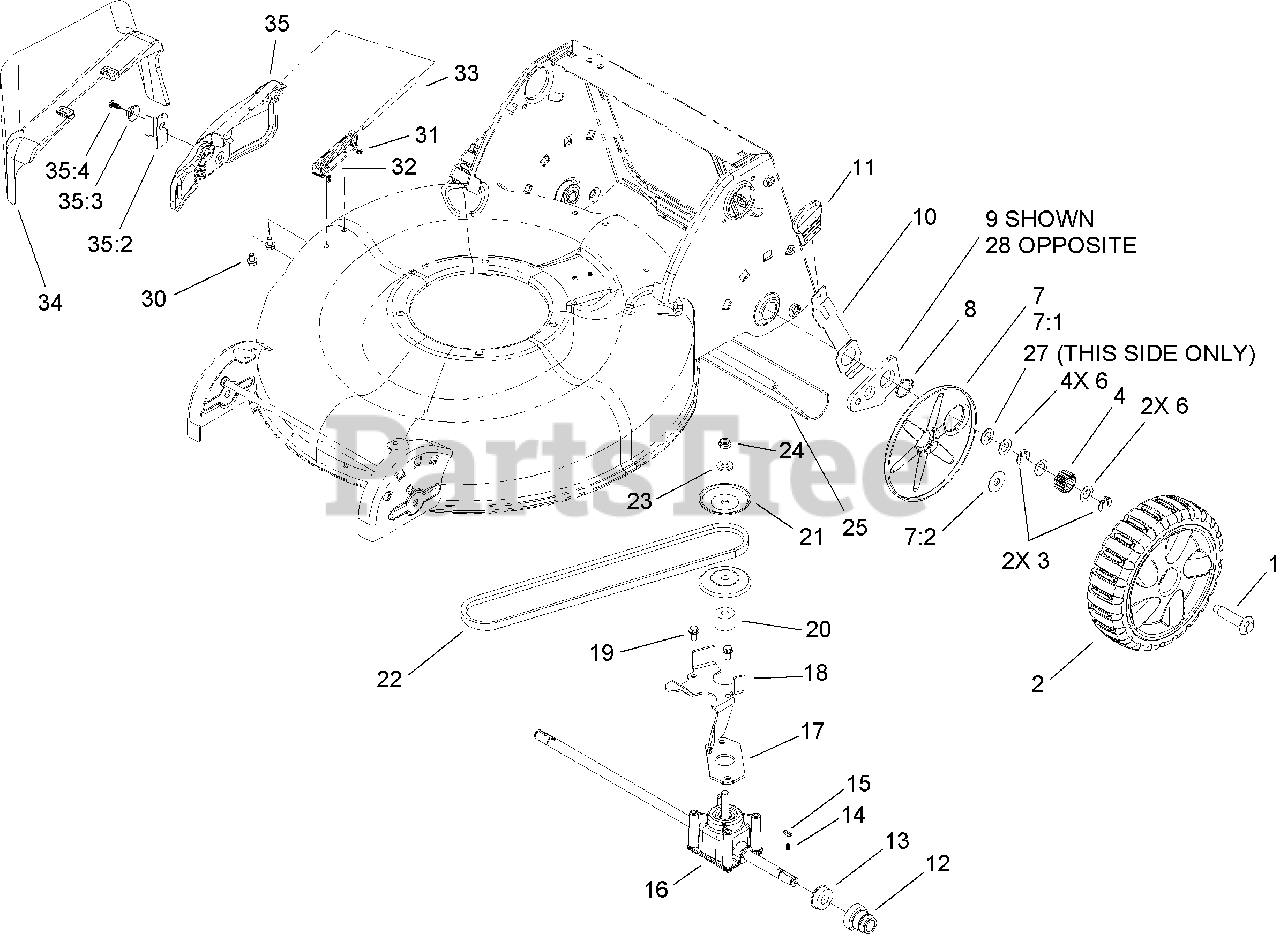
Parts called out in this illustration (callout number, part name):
1	BOLT-SHOULDER
2	REAR WHEEL ASM
3	KLIPRING-LOCKING
4	Gear-Pinion, 15t
6	Washer-Thrust
7	WHEEL COVER ASM
7:1	COVER-WHEEL
7:2	WASHER-STEPPED
8	RING-RETAINING
9	ARM-REAR PIVOT, LH
10	ARM-SPRING, REAR
11	KNOB-LEVER, HOC
12	RETAINER-BEARING, HOC
13	BEARING-BALL
14	SPRING-COMPRESSION
16	TRANSMISSION ASM
17	GASKET-GEARBOX
18	BRACKET-TRANSMISSION
19	SCREW-HWH
21	PULLEY-HALF
23	WASHER-FLAT
24	NUT-LOCK
25	SHIELD-TRAILING
28	ARM-REAR PIVOT, RH
30	SCREW-HWH
31	SPRING-TORSION
32	BRACKET-COVER
33	ROD-COVER
34	CHUTE-DISCHARGE, SIDE
35	DISCHARGE DOOR ASM
35:2	LATCH-DOOR
35:3	CAP-DOOR
35:4	SCREW-PLASTITE
